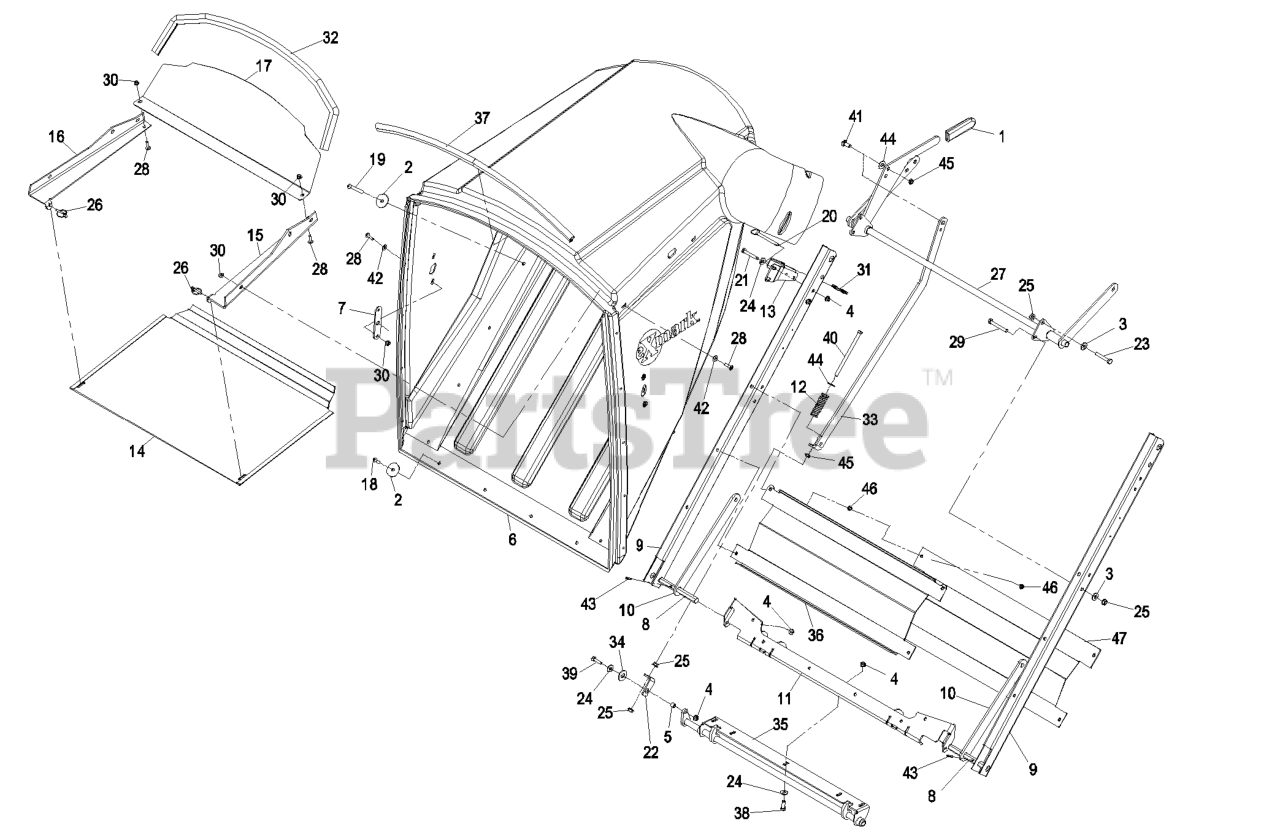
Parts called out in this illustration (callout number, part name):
1	GRIP-LEVER
3	WASHER-BELLEVILLE
4	NUT-HF, NI
5	BUSHING, LOCATOR
6	HOPPER,FR 12 BUSHEL
7	PLATE,FR LWR PVT BACKING
8	SHAFT,.625 HEX
10	LINK,FR HOPPER PIVOT
12	SPRING-COMPRESSION
13	BRACKET,FR HNDL STORAGE
14	SCREEN,FR HOPPER
16	ANGLE,LH FR SCRN SUPT
17	BAFFLE,FR HOPPER SCREEN
18	SCREW-HSBH
19	SCREW,HSPH
20	PIN-HITCH, COTTERLESS
21	SCREW-HH
22	LINK,BRAKE (PLATED)
23	SCREW-HH
24	WASHER-FLAT
25	NUT-HHF, WHIZ
26	PIN-KLIK
28	SCREW-TTH
29	SCREW-HH
31	STRIP-SEAL
32	SEAL,TRIM 38.00
33	LINK,FRUVD LATCH
34	WASHER-FLAT
35	WLD,FRUVD LATCH
36	SHIELD,FRUVD INNER HEAT
37	SEAL,SIDE TRIM 34.50 X .1
38	SCREW-HH
39	SCREW-HH
40	BOLT-TAP, HH
41	SCREW-CARR
42	WASHER-FLAT
43	PIN-SPRING
44	WASHER-FLAT
46	NUT-LOCK, NI
47	SHIELD,FRUVD OUTER HEAT
48	Asm, Latch Link
